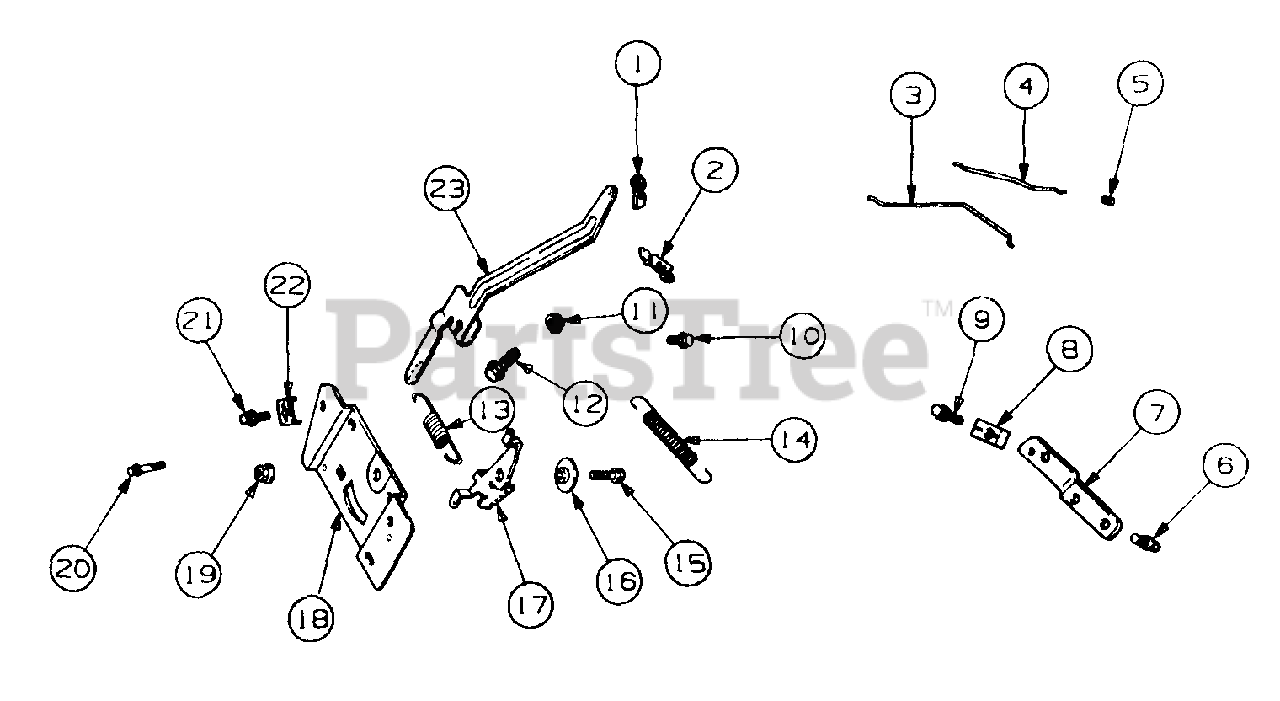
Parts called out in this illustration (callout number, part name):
1	Bushing, Throttle
2	Lever, Choke, Upper
3	Linkage, Choke, Upper
4	Linkage, Throttle
5	Bushing, Linkage
6	Screw, Bracket, M5 x .8 x 10
7	Bracket, Choke Mount
8	Clamp, Cable
9	Screw, Clamp, M5 x .8 x 16
10	Screw, M5 x .8 x 10
11	Nut, M6x1
12	Screw, Governor Arm, M6 x 1 x 25
13	Spring, Governor
14	Spring, Linkage
15	Screw, Throttle Cntrl, M5 x .8 x 16
16	Spacer, Throttle Control
17	Lever, Throttle Control
18	Plate, Control
19	Nut, Hex, M5 x .8
20	Screw, Control Plate, M6 x 1 x 16
21	Screw, Cable Clamp, M5 x .8 x 16
22	Clamp, Cable
23	Lever, Governor
